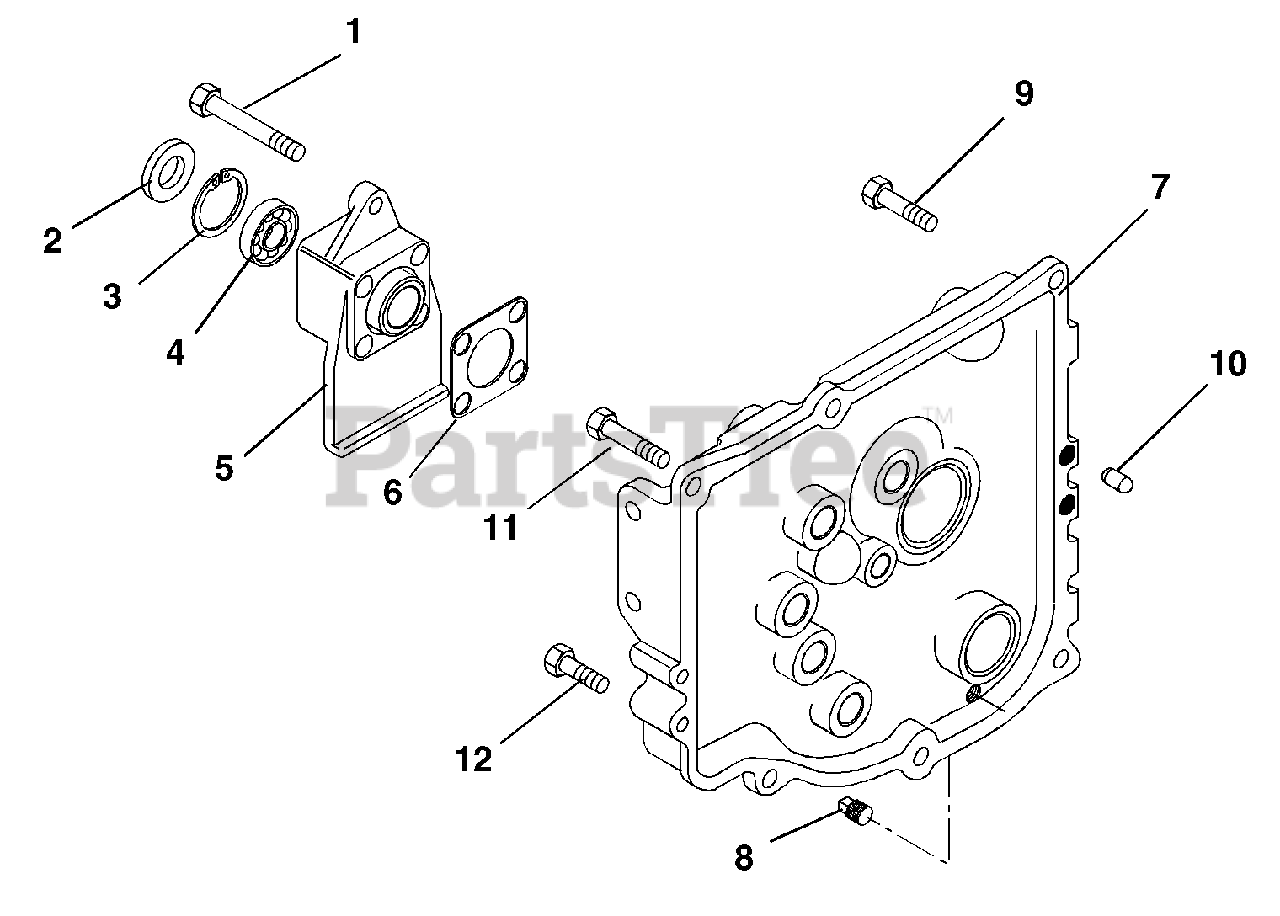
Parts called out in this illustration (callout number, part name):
1	Bolt-Hex .50-13 X 3.25 Grade 5
2	Seal 1.25 x 2.25 x .50
3	Ring-Retaining-External 2.49 x .078
4	Bearing-Ball 1.25 x 2.25 x .50 Sealed
5	Axle Bearing Retainer
6	Gasket
7	Assembly, Transmission Cover
8	Plug-Pipe .38 Square Head Unfinished Steel
9	Bolt-Hex .38-16 x 2.00 Grade 5
10	Pin-Dowel .38 x .63
11	Bolt-Hex .38-16 x 2.25 Grade 5
12	Bolt-Hex .38-16 x 1.50 Grade 5
